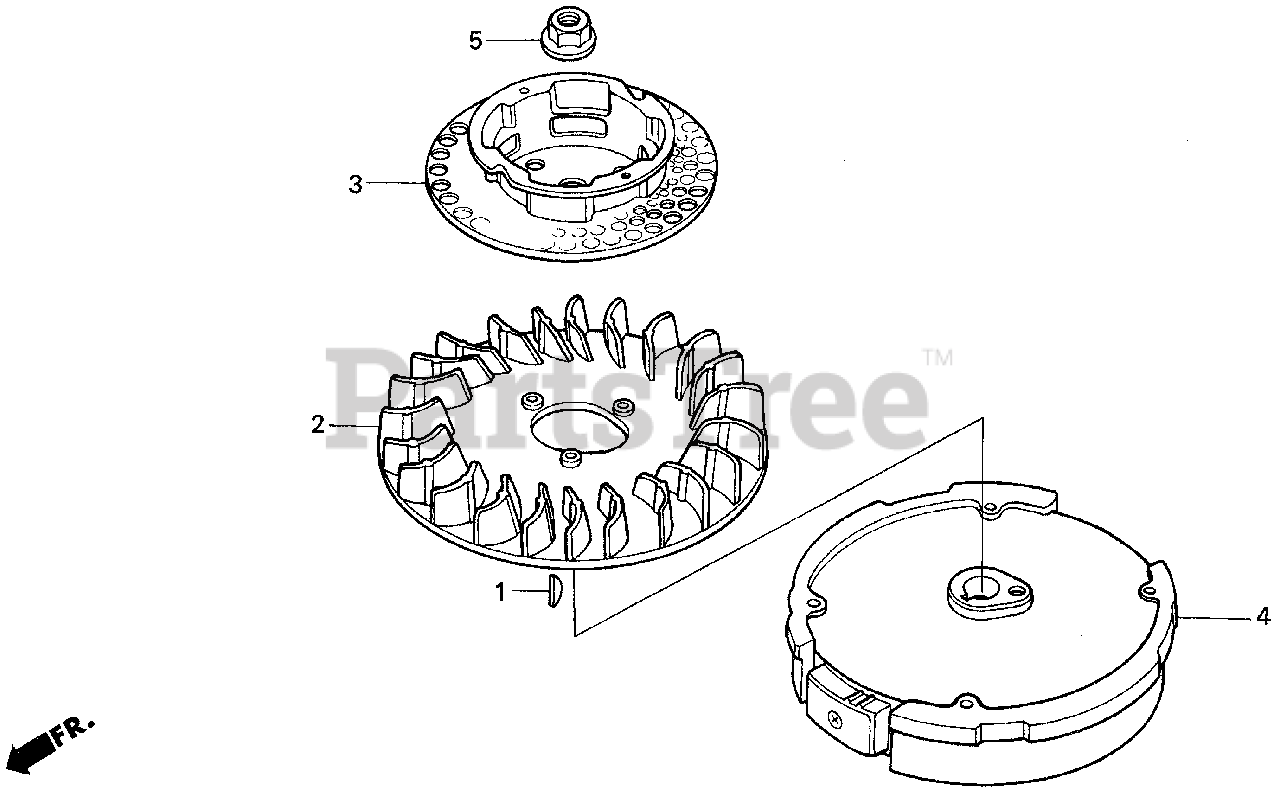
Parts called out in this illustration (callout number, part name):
1	KEY, SPECIAL WOODRUFF (25X18)
2	FAN, COOLING
3	PULLEY, STARTER
4	FLYWHEEL
5	NUT, SPECIAL (14MM)
